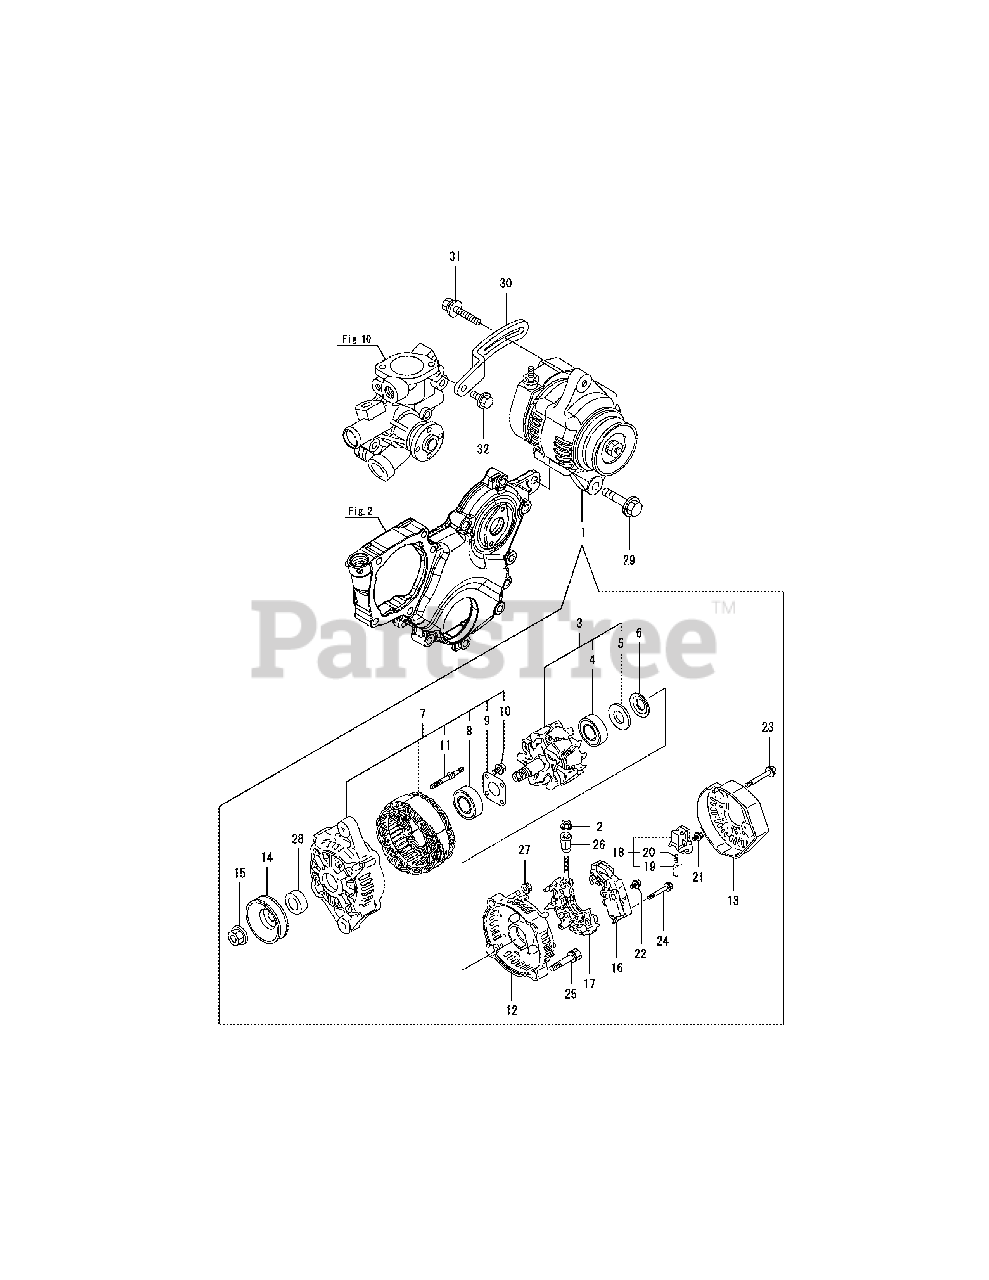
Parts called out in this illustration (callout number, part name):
1	GENERATOR, 40A
5	COVER, BEARING
6	WASHER, THRUST
7	FLAME ASSY, DRIVE
9	PLATE, RETAINER
12	FLAME ASSY, REAR
13	COVER, REAR END
16	REGULATOR ASSY
26	BUSH, INSULATION
29	BOLT M10X 45 PLATED
30	ADJUSTER, BELT
32	BOLT M 8X 20 PLATED
